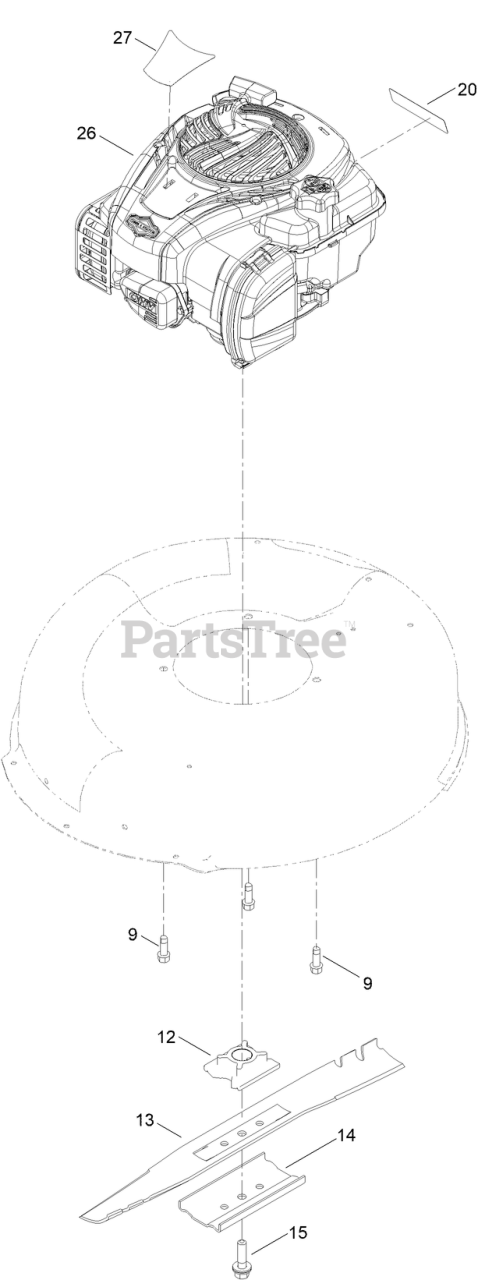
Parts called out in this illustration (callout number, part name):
9	SCREW-TAPTITE
12	RETAINER-BLADE
14	SUPPORT-BLADE
15	BOLT-BLADE
20	DECAL-ARRESTOR, SPARK
26	ENGINE-BRIGGS, 550 EX
27	DECAL-ENGINE
